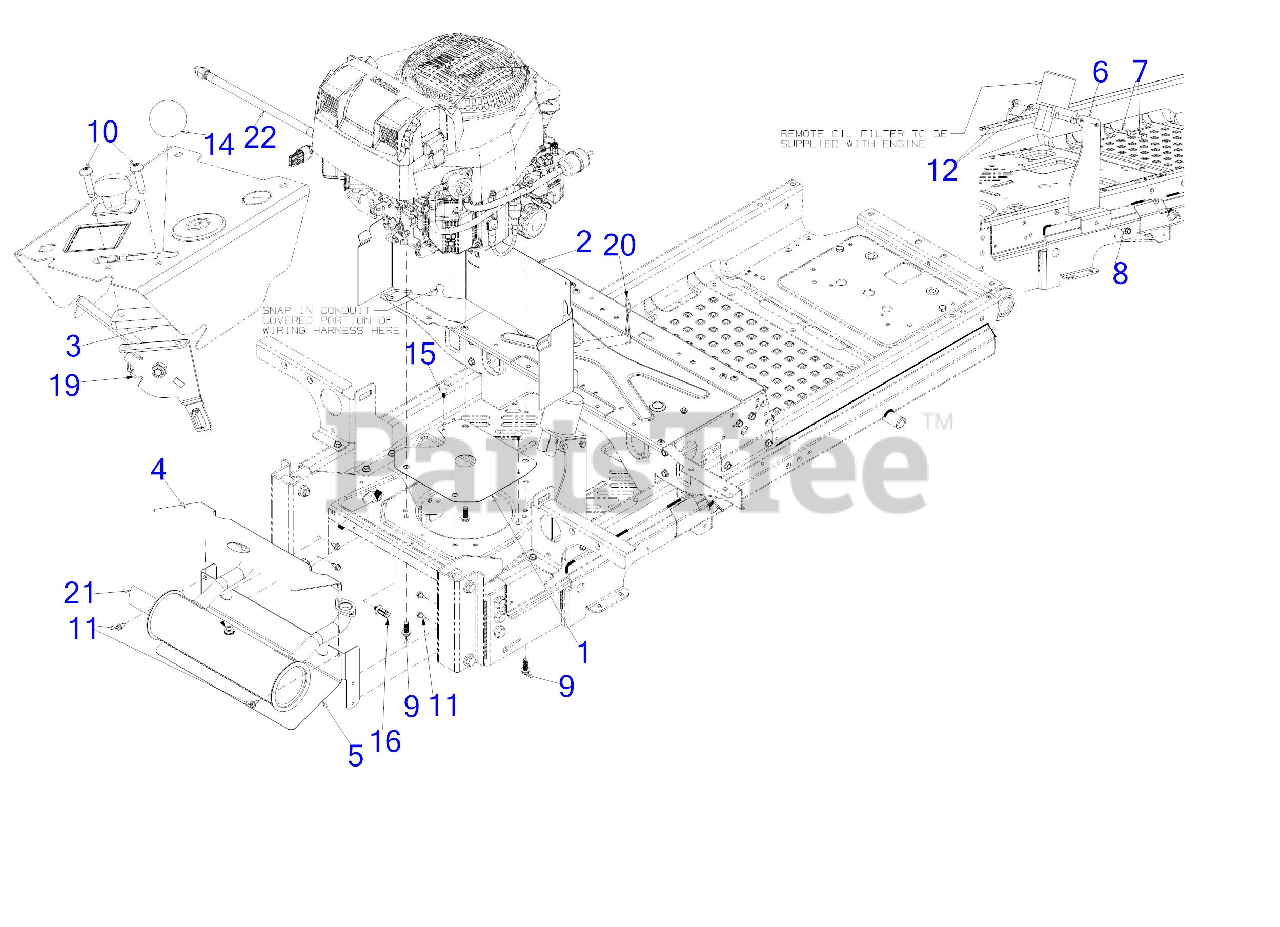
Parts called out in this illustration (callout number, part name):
1	ENGINE SHIELD PLATE
4	MUFFLER SHIELD-TOP
5	MUFFLER SHIELD-BOTTOM
7	SCREW 5/16-18 x 1.0 GR5
8	SCREW 5/16-18 x .750
9	SCREW 3/8-16 x 1
10	SCREW 1/4-20 x 1.0
11	SCREW 1/4-20X.625
12	FLANGE LOCK NUT 5/16-18
15	RATCHET CLIP .250
16	DRAIN HOSE CLIP
19	THROTTLE CABLE 59"
20	TANK SUPPORT ROD
21	ROUND TWIN MUFFLER
22	OIL DRAIN HOSE
